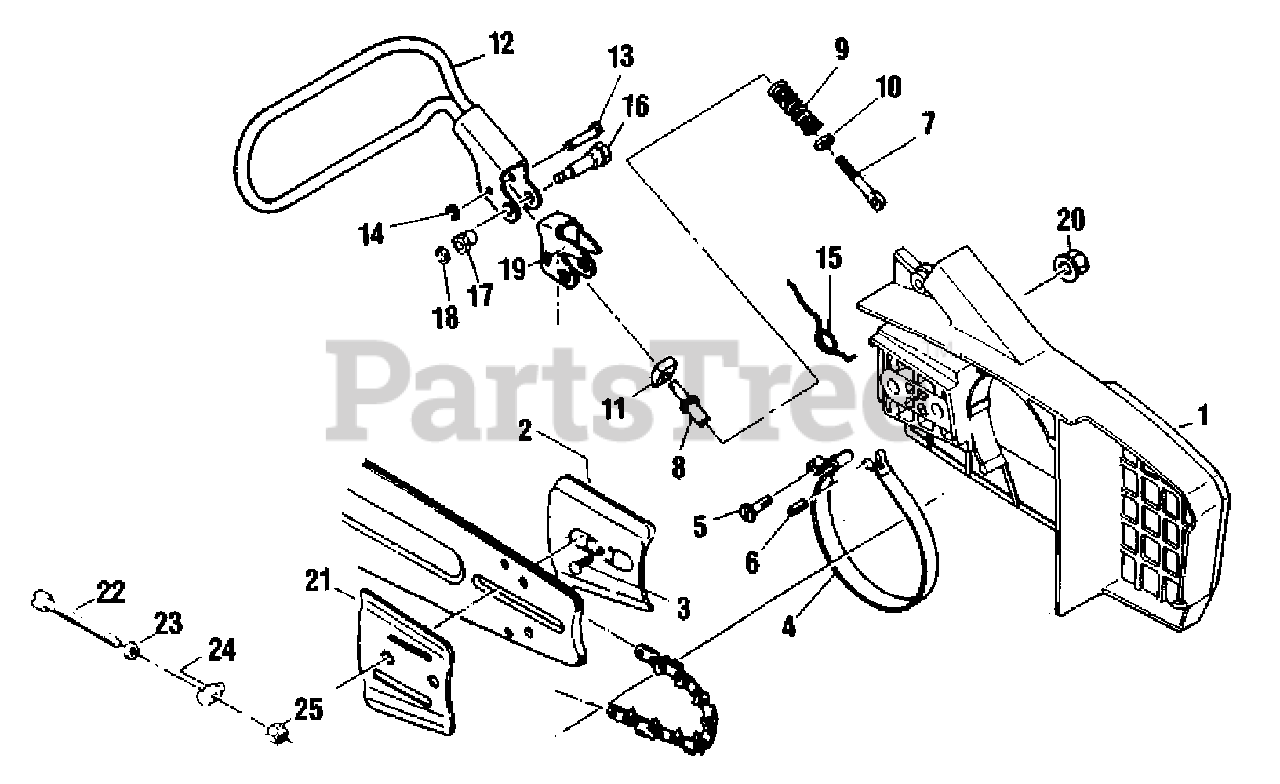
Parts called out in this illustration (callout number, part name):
1	COVER, CLUTCH
2	PLATE, GUIDE - OUTER
4	BAND, BRAKE
5	BOLT
6	PIN, SPRING
7	ROD, ADJUST
8	SCREW, ADJUST
9	SPRING, BRAKE
12	LEVER
13	STOPPER PIN
14	RING, RETAINING
15	RELIEF SPRING
16	BOLT, LEVER
17	NUT
18	RING, SNAP 3 MM
20	NUT
21	PLATE, GUIDE - INNER
22	SCREW, ADJUST
23	WASHER, FLAT 5.5×10×0.8
24	STUD, ADJUST
25	LOCKNUT
